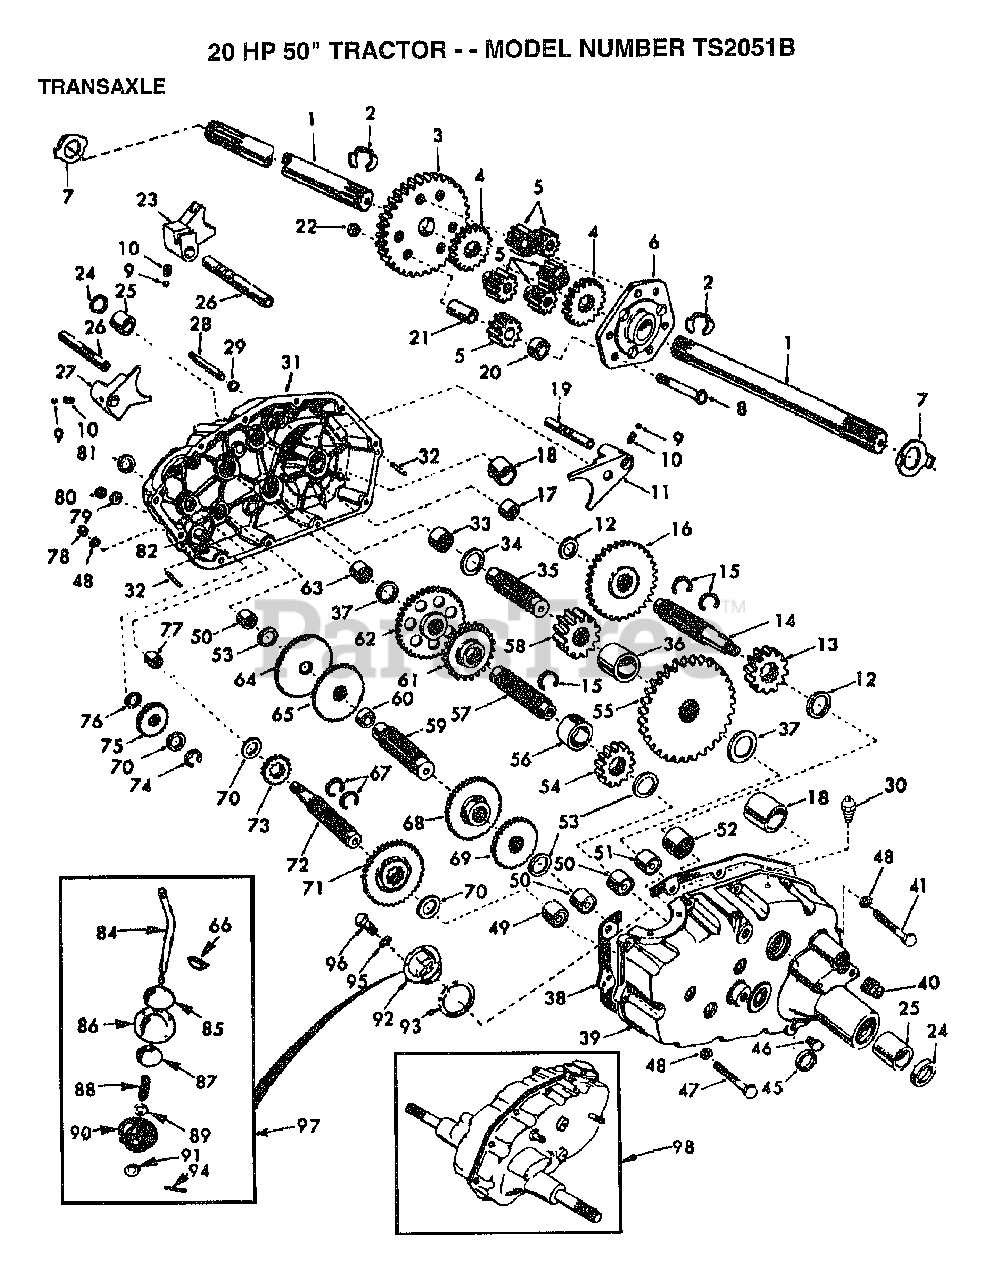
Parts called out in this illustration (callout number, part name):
1	SHAFT.AXLE.T
2	KLIP RING
3	FINAL GEAR T
4	DIFF GEAR T
5	DIFF PINION T
6	DIFF CARRIER T
8	BOLT
11	SHIFT FORK T
12	WASHER .T
13	RED PINION T
14	GEAR SHAFT T
15	SNAP RING T
16	GEAR T
17	"T, BEARING"
18	BEARING
19	SHAFT
20	SPACER T
21	PINION RS
22	GRIPCO NUT
23	FORK T
24	OIL SEAL STD
25	BRNG. T
27	SHIFT FORK T
28	SHIFT SHAFT
29	SEAL T
30	VALVE M
32	PIN T
33	NEEDLE BRNG T
34	RACE T
35	GEAR SHAFT T
37	RACE T
38	GASKET
40	PLUG PIPE
41	BOLT
45	SEAL T
47	HEX BOLT
48	LOCKWASHER
49	"TI, BEARING"
50	NEEDLE BRNG T
51	NEEDLE BRNG T
52	"STD, BEARING"
53	BRNG RACE
54	RED PINION T
55	RED GEAR T
56	PINION SPACER T
57	GEAR SHAFT T
58	FINAL PINION T
59	GEAR SHAFT T
60	SPACER T
61	RED PINION T
62	RED GEAR T
63	RACE T
64	LOW SPEED GEA T
65	REVERSE GEAR T
66	KEY T
67	RING STD
68	INTERMED GEAR T
70	"T, BEARING"
71	CLUSTER GEAR T
72	INPUT SHAFT T
73	LO SPEED PINION T
75	IDLER GEAR T
76	WASHER T
77	NEEDLE BEARING TI
78	NUT.HEX.5/16-18
79	WASHER T
80	NUT
81	SEAL STD
84	GEAR SHIFT LVR T
85	CAP T
86	COVER AND PIN T
87	GUIDE BALL T
88	SPRING TI
89	WASHER
90	SEAL T
91	WASHER
92	GEAR SHIFT GA T
93	GASKET T
94	COTTER PIN
95	LOCKWASHER
96	BOLT
97	GEAR SHFT LVR T
98	TRANSAXLE.6SP.GT
